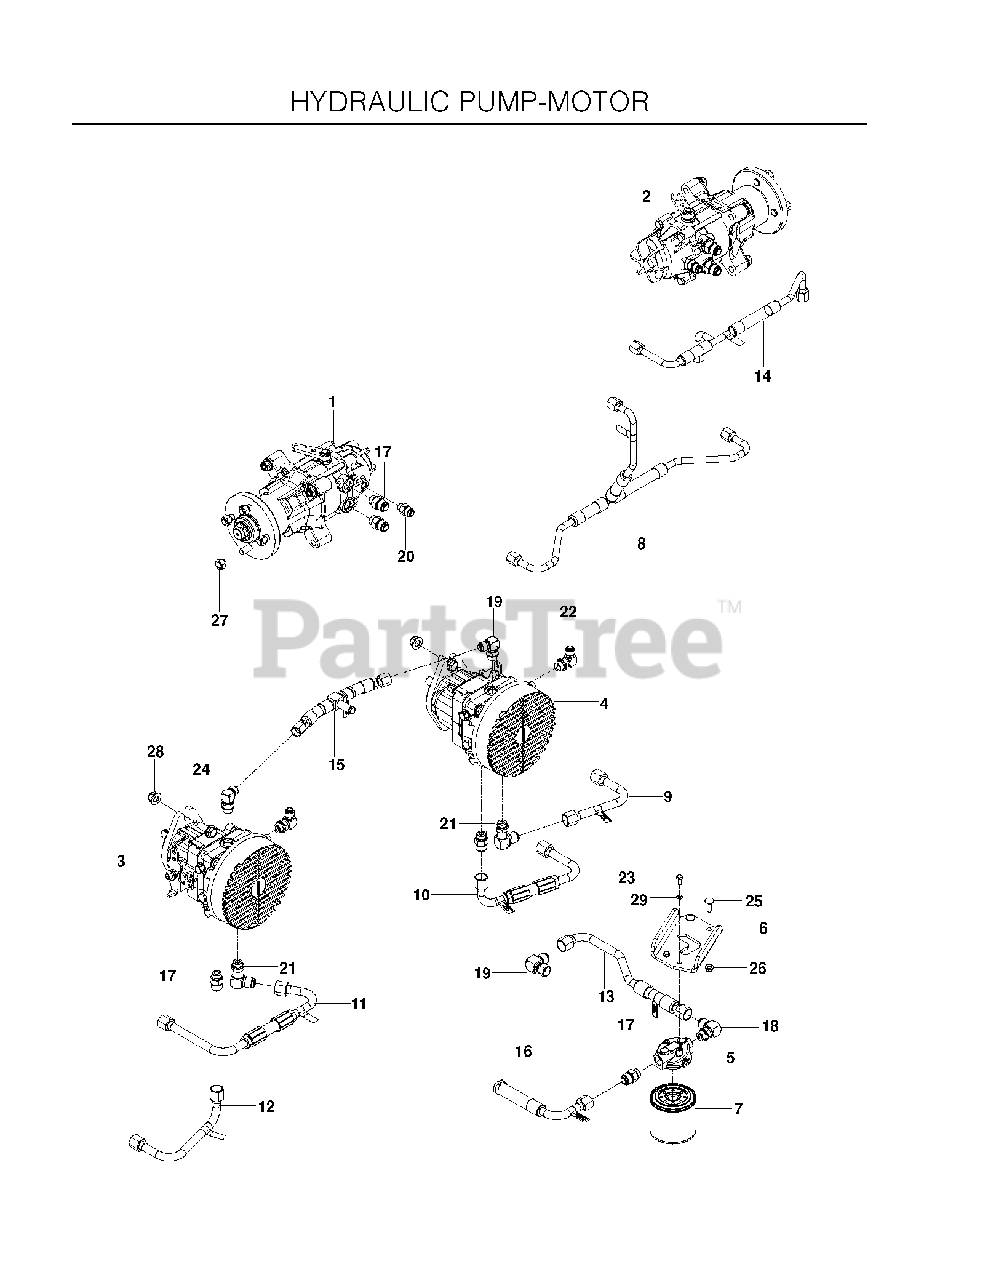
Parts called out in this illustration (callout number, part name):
1	MOTOR, PRM, RT
2	MOTOR, PRM, LT
3	PUMP, 21CC, RT
4	PUMP, 21CC, LT
5	FILTER HEAD
6	MOUNT, FILTER, BLK
7	FILTER 25 MICRON
8	LINE, HYD, CASE-RM
9	LINE, HYD, LT-AA
10	LINE, HYD, LT-BB
11	LINE, HYD, RT-AB
12	LINE, HYD, RT-BA
13	LINE, HYD, SUCTION
14	LINE, HYD, PUMP
15	LINE, HYD, CHARGE
16	LINE, HYD, CHARGE
17	FITTING, 10-8 STRAIGHT
19	FITTING, HYD, 6500-10-8
20	FITTING, HYDRO
21	FITTING, 10-8 90 DEG
22	ELBOW, 90 DEGREE
23	HCS 1/4C X 5/8
24	HCS 1/2C X 1 1/4 SERRATED HEAD
25	RHSNB 5/16C X 1
26	5/16-18 NYLOC FLANGE NUT
27	LUG NUT 1/2F
28	NUT, 1/2-13 HEX FLG NYLOC ZD
29	LOCKWASHER 1/4"
